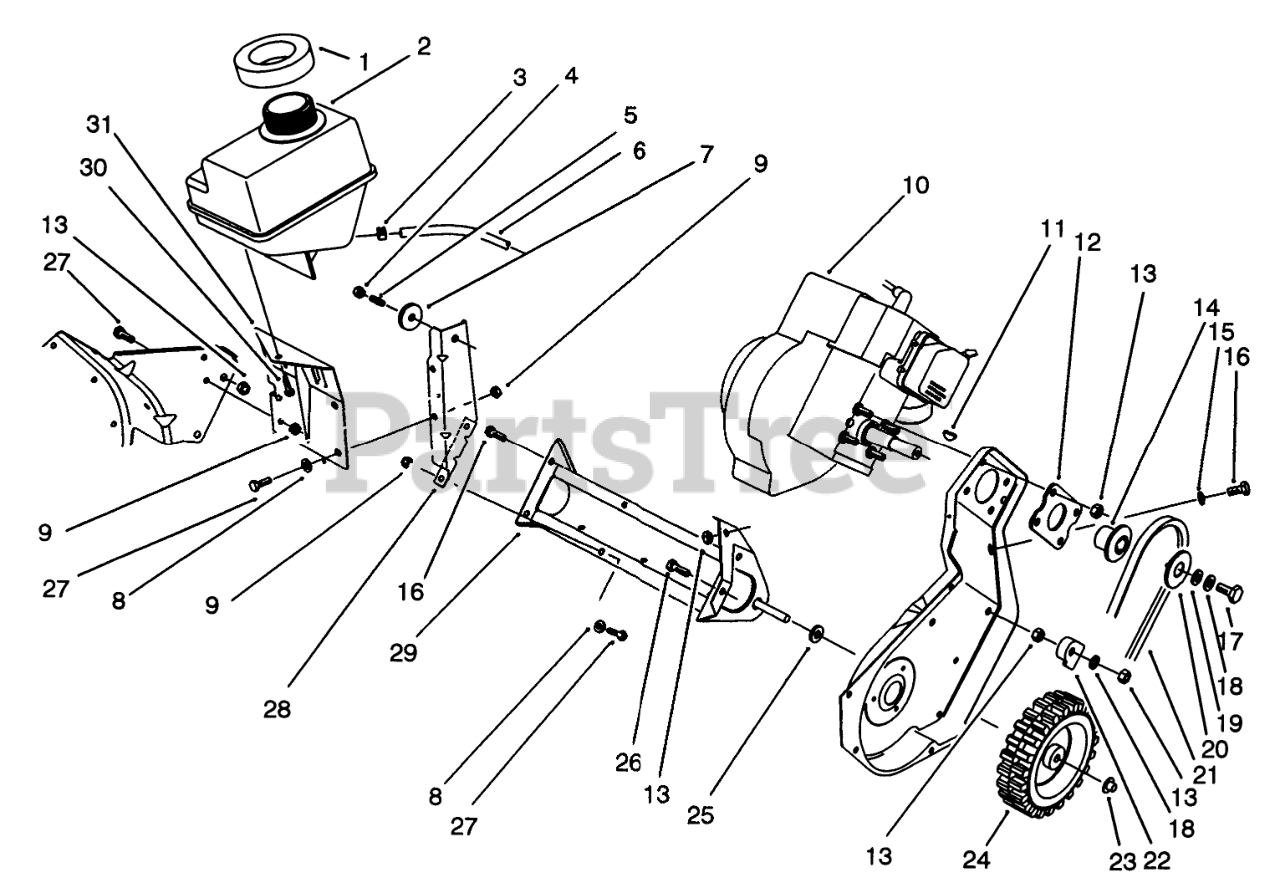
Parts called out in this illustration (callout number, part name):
1	SEAL-FOAM
2	Tank-Gas
3	Clamp
4	NUT-LOCK, NI
6	LINE-FUEL
7	WASHER-SUPPORT, ENGINE
8	WASHER-FLAT
9	NUT-LOCK, NI
10	Engine (Model No. 38190-Tec.No. HSK600-1659R) (Model No. 38191-Tec. No. HSK600-1671 R)
11	KEY-WOODRUFF
12	Plate Engine
13	NUT-LOCK, NI
14	Hub-HALF SHEAVE
15	WASHER-PLAIN
16	SCREW-HH
17	SCREW-HH
18	WASHER-BELLEVILLE
19	WASHER-FLAT
20	CAP-HALF SHEAVE
21	V-BELT
22	GUIDE-CABLE
23	RETAINER-PUSH ON
24	WHEEL
25	SPACER-PLASTIC
26	SCREW-HH
27	SCREW-HH
28	Support-Engine
29	Frame Assembly
30	SCREW-SHWH, THREAD FORMING
31	Bracket-Fuel Tank
